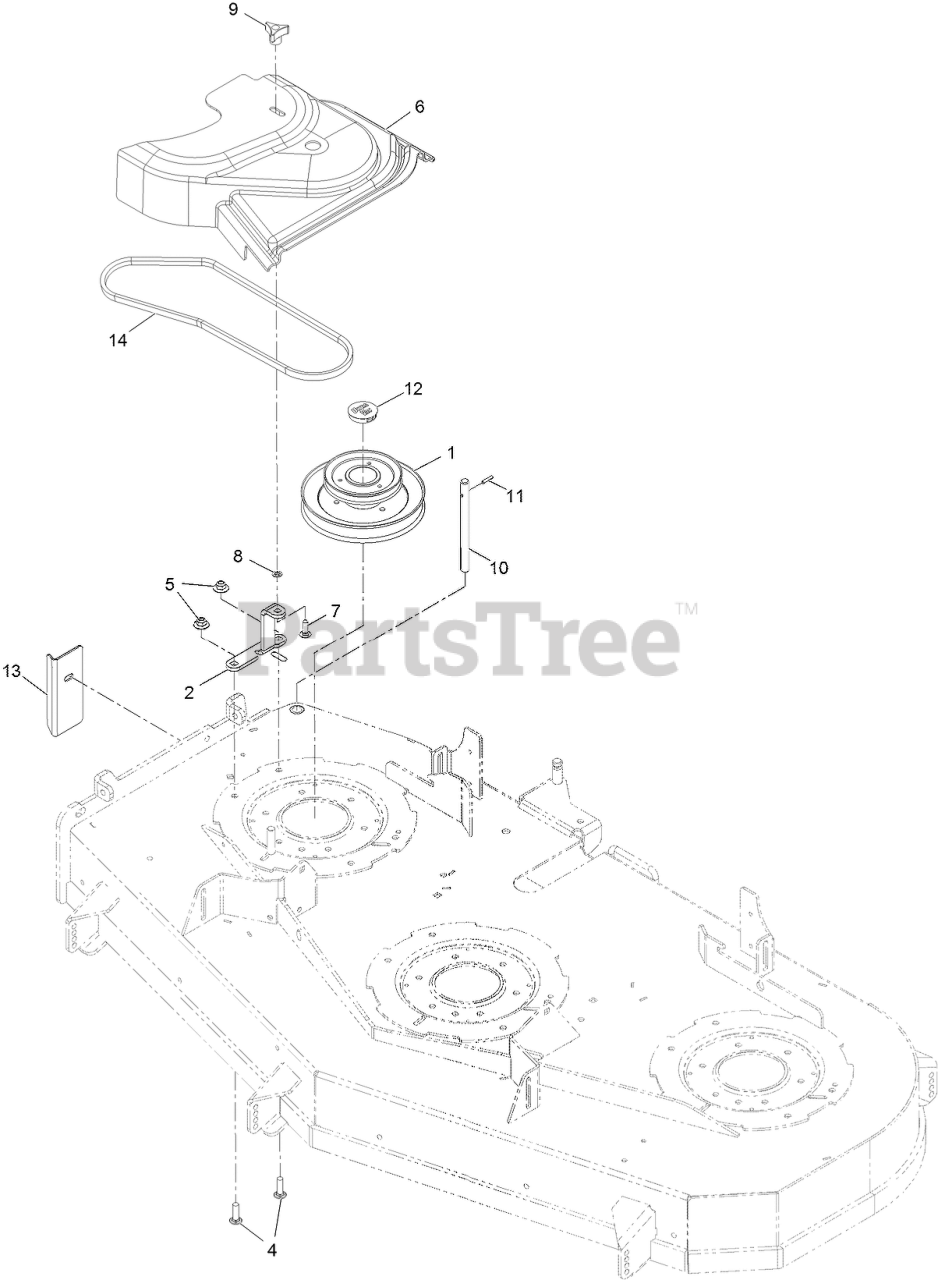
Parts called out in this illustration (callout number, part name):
1	JACKSHAFT,UV DRIVE 604 SPLINED
2	BRACKET-BELT COVER
4	Bolt-Carriage 3/8-16 X 1 1/4
5	Nut-Nyloc 3/8-16 Flg
6	COVER-BELT UVE 60
7	BOLT-CARR
8	RING-RETAINING, BOLT
9	KNOB-3 PRONG
10	SHAFT-CATCHER, GRASS
11	PIN-ROLL
12	PLUG, BLACK NYLON 1.75
13	PLATE-BLOCKER
14	BELT- 4L SECTION
